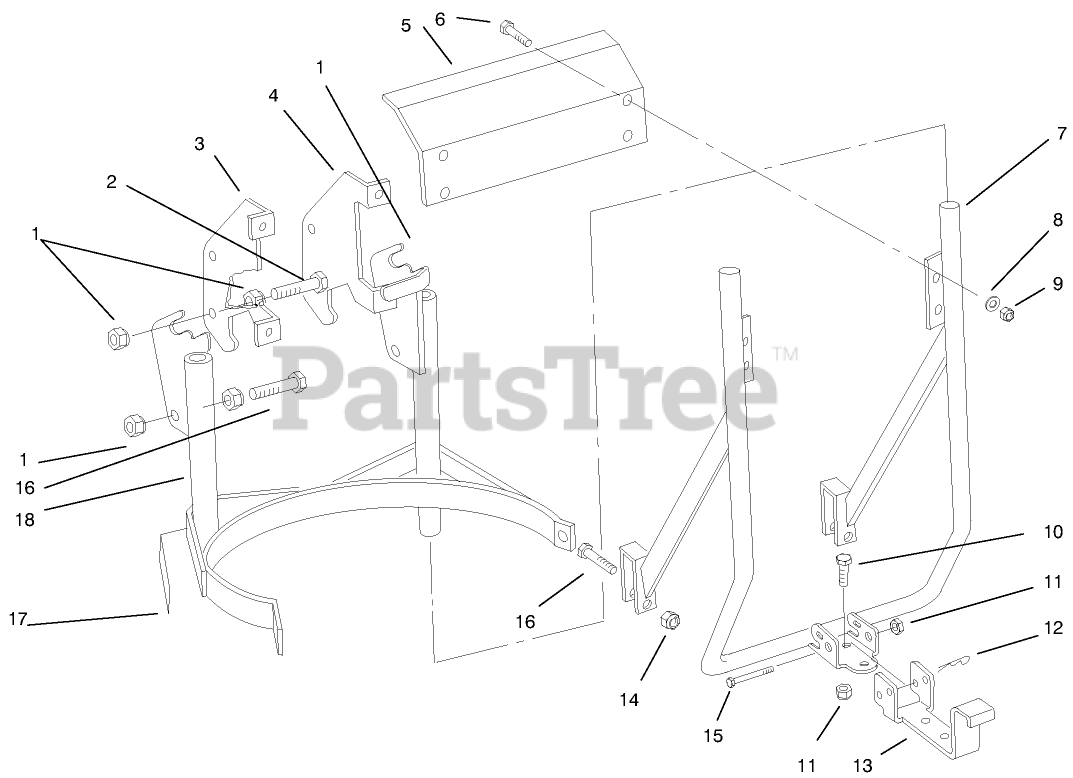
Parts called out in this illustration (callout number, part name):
1	NUT-HEX
2	SCREW-HH
3	LH TOP BRACKET B
4	RH TOP BRACKET B
5	SHIELD-HEAT B
6	SCREW-HH
7	MOUNT-BAGGER W.A. B
8	WASHER-PLAIN
9	NUT-LOCK, NI
10	SCREW-HH
11	NUT-LOCK, NI
12	PIN-COTTER, HAIR
13	BRACKET-SUPT B
15	NUT-LOCK, NI
16	SCREW-HH
17	DECAL-DANGER
18	Support, Canister Asm (Incl. Ref. 17)
